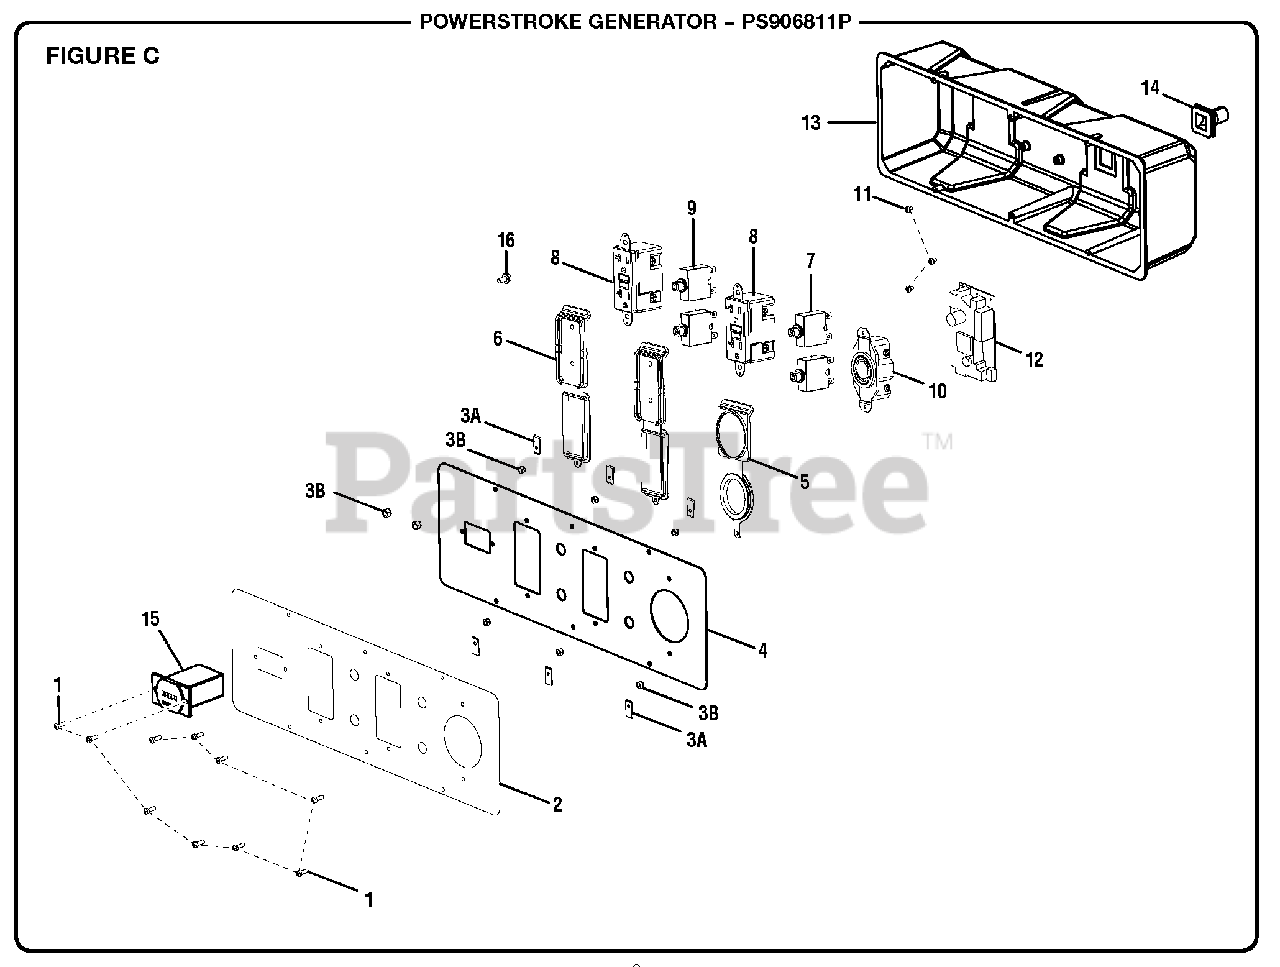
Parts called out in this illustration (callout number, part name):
1	Screw (6-20 x 3/8 in.)
2	Outlet Panel Label
3	U- Clip Nut (#6)
4	Front Panel
5	240 Volt Outlet Covers
6	120 Volt Outlet Covers
7	Circuit Breaker (30 Amp)
8	120 Volt Duplex Receptacle
9	Circuit Breaker (20 Amp, 125 Volt)
10	Twist Lock Receptacle (120/240 Volt, 30 Amp, L14-30R)
11	Screw (M3 x 5 mm)
12	Battery Charger Assembly
13	Control Box (Back Panel)
14	Rubber Boot (Control Panel Assembly)
15	Hour Meter
16	Bolt (M5 x 10 mm, Hex Flange Hd.)
